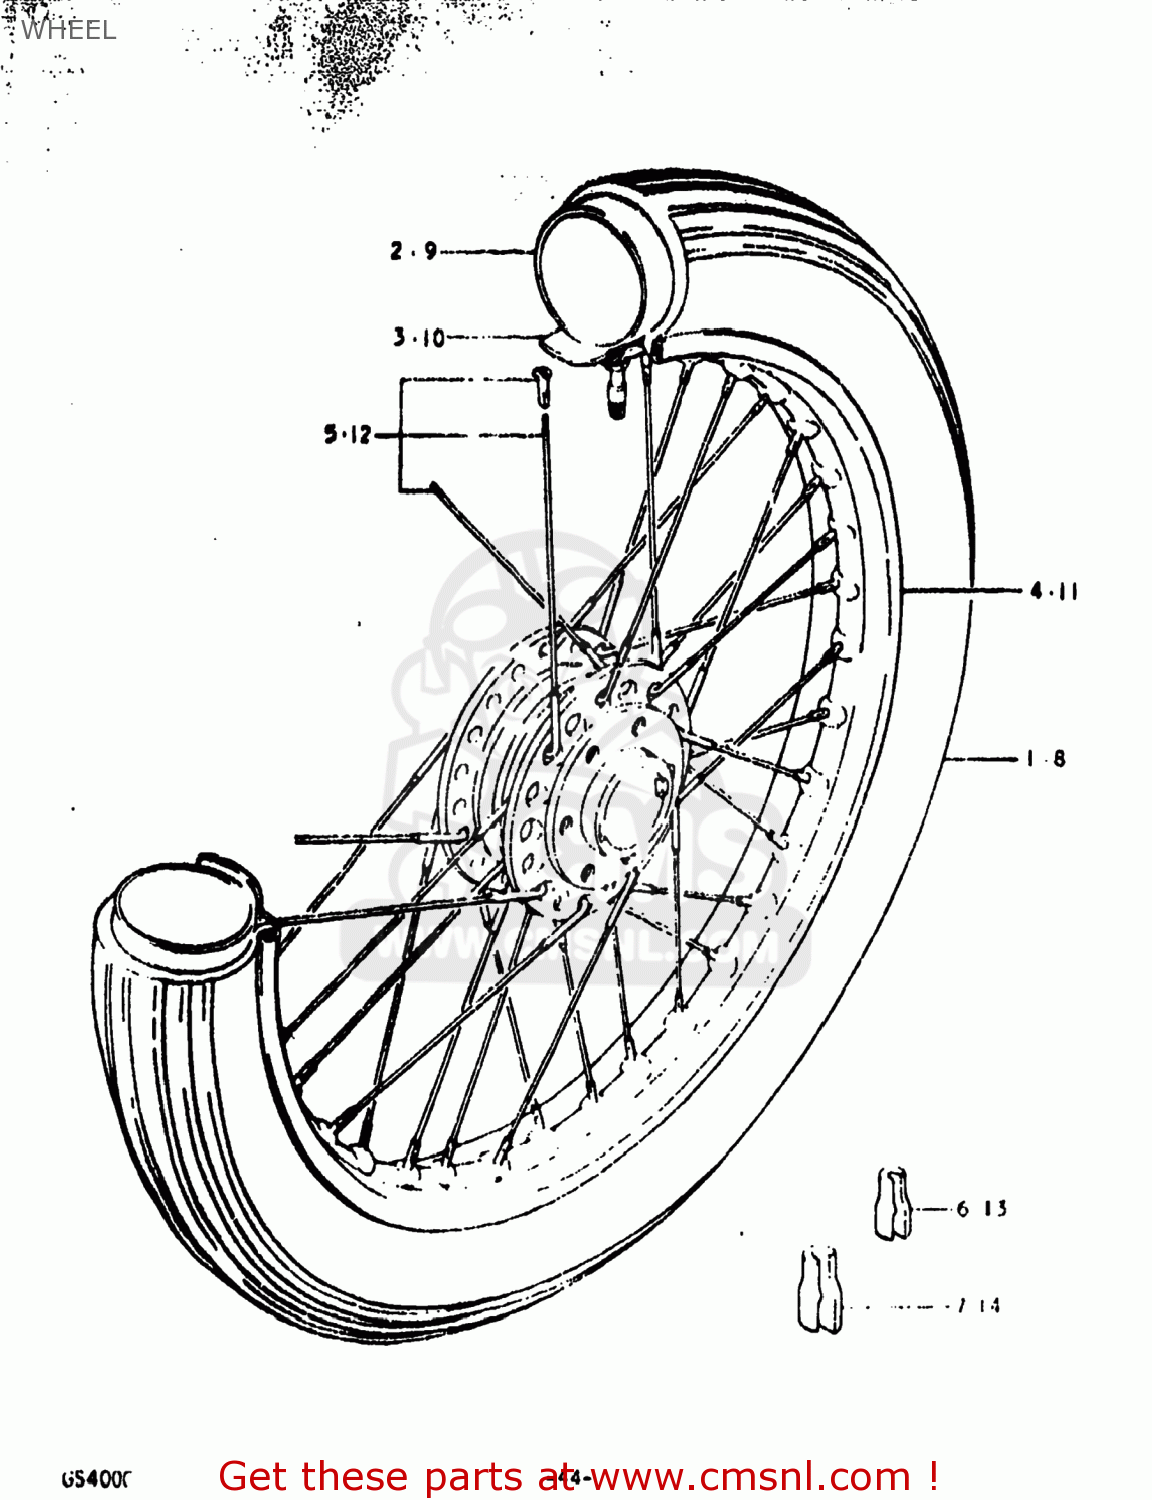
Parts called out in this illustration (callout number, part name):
1	HEADLAMP ASSEMBLY
2	TUBE,INNER
3	PROTECTOR,WHEEL,INNER
4	RIM,FR WHEEL
5	SPOKE SET,FRONT
6	BALANCER,WHEEL (B)
7	BALANCER,WHEEL (30G)
8	TIRE
9	TUBE ASSEMBLY,WHEEL,INNER
10	PROTECTOR,INNER TUBE
11	RIM,RR WHEEL
12	SPOKE SET,REAR WHEEL
13	BALANCER,WHEEL (B)
14	BALANCER,WHEEL (30G)
